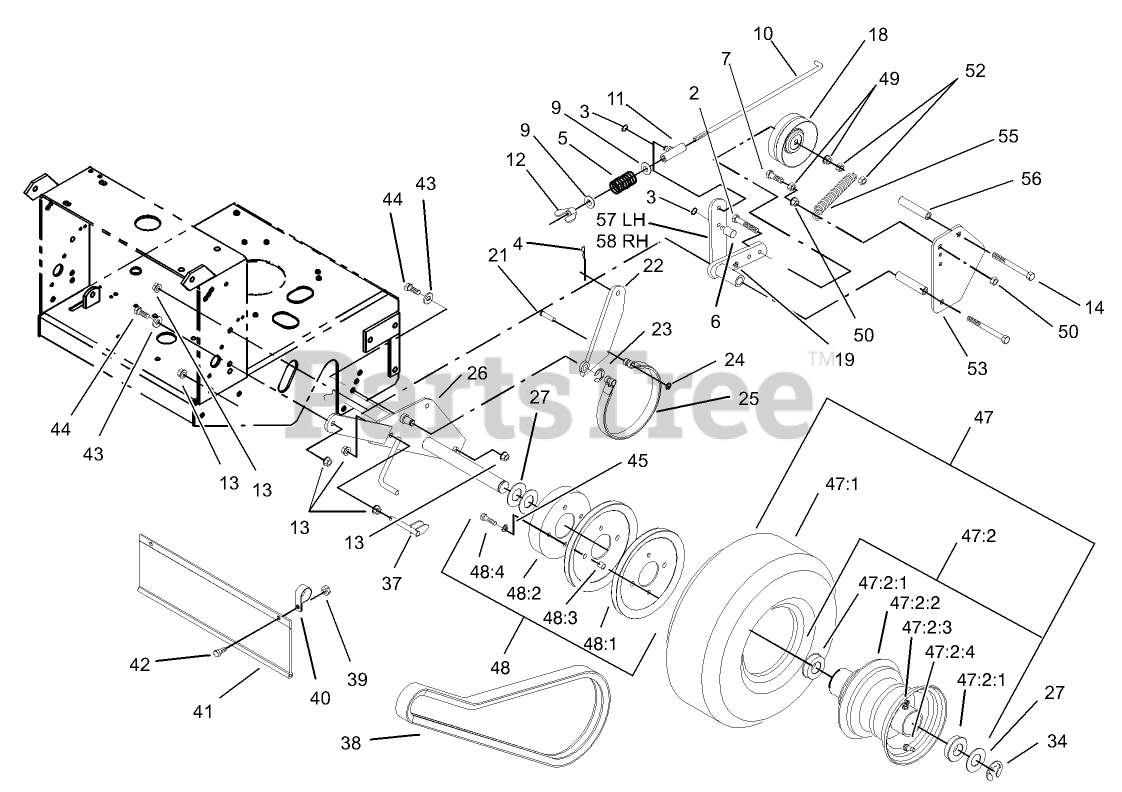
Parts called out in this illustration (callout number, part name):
2	SCREW-HH
3	RING-RETAINING
4	PIN-COTTER
5	SPRING-COMPRESSION
6	Swivel-Lever, Drive
7	SCREW-HH
9	WASHER-PLAIN
10	Linkage-Brake
11	SWIVEL-BRAKE
12	WINGNUT-NYLOCK
13	NUT-HHF, WHIZ
14	SCREW-HH
18	IDLER-WHEEL, DRIVE
19	FITTING-GREASE
21	PIN-CLEVIS
22	ARM-BRAKE
23	RING-RETAINING, EXTERNAL
24	NUT-PUSH
25	BAND-BRAKE
27	WASHER-SPACER
34	RING-SNAP
37	SCRAPER
38	V-BELT
39	NUT-LOCK, NI
40	CLAMP-R
41	SHIELD-TRAILING
42	SCREW-HH
43	WASHER-BELLEVILLE
44	SCREW-HH
45	WASHER
47	WHEEL AND TIRE ASM
47:1	Tire-Turfmaster
47:2	WHEEL AND HUB ASM
47:2:1	BEARING-FLANGED
47:2:2	Rim ASM
47:2:3	Fitting-Grease
47:2:4	Stem-Valve
48	Drum and Sheave ASM
48:1	SHEAVE-WHEEL, DRIVE
48:2	DRUM-BRAKE
48:3	SPACER-SHEAVE, WHEEL
48:4	SCREW-HH
49	NUT-HHF, WHIZ
50	NUT-HF
52	NUT-LOCK, NI
53	Shield-Wheel, Drive
55	SPRING-EXTENSION
56	SPACER-SHIELD
57	Arm-Idler, LH
58	Arm-Idler, RH
